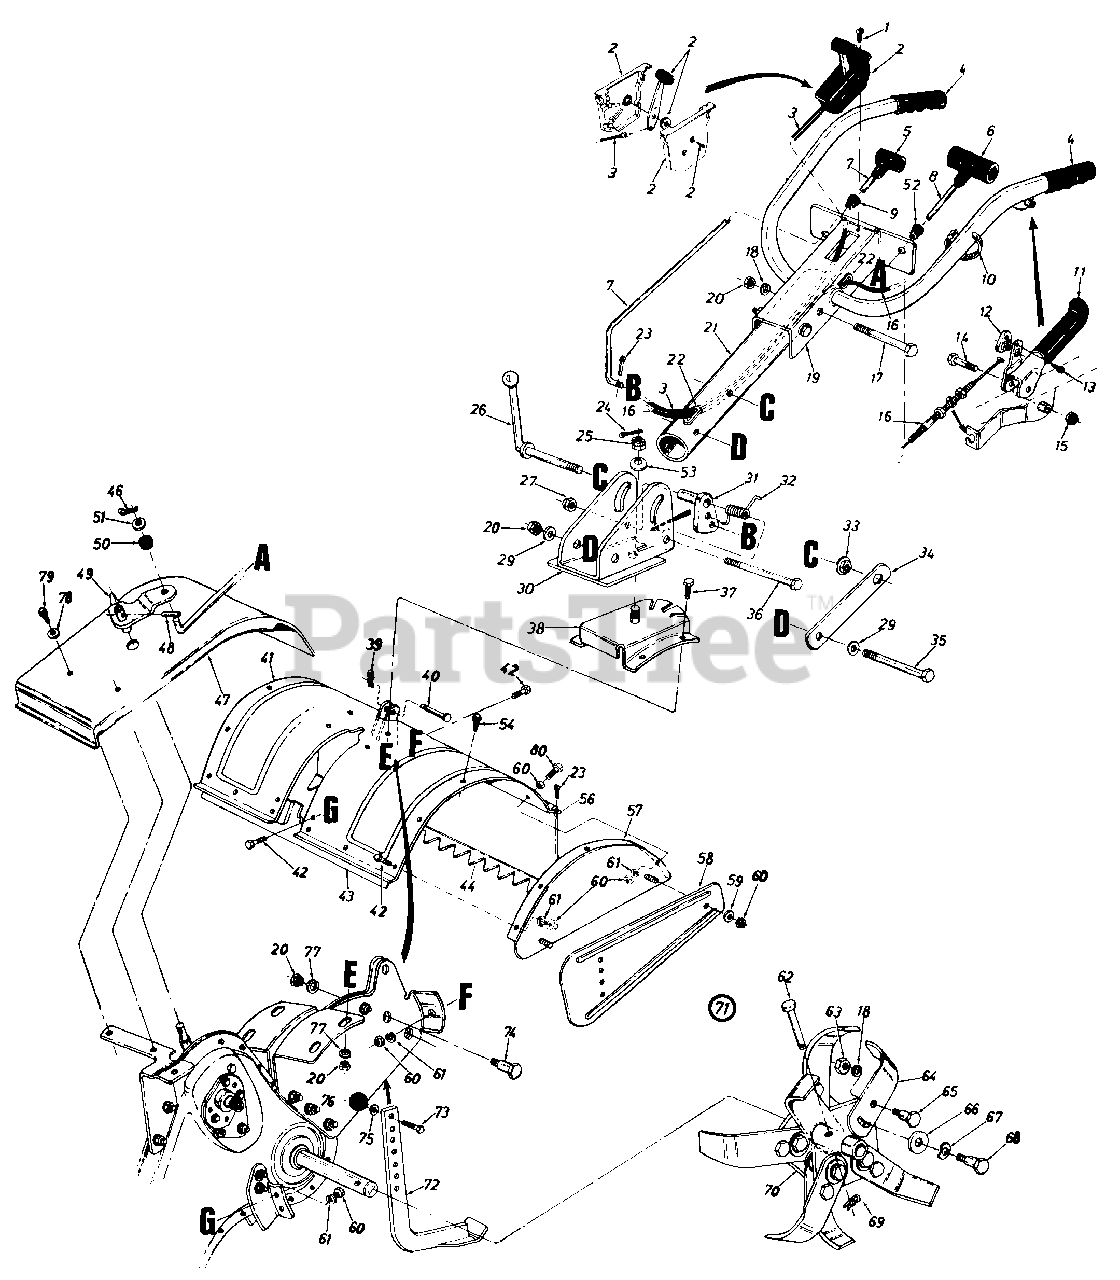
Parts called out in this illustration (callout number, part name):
1	Truss Mach. AB-Tap. Scr. #10 x .50' Lg.
2	Throttle Control Box Ass'y.
3	Throttle Control Wire
4	Handle Grip
5	Small "T" Knob
6	Large"T" Knob
7	Clutch Rod
8	Control Rod 37" Lg.
9	Snap On Bushing 3/8" Dia.
10	Cable Tie-Self Clinching
11	Clutch Grip Ass'y.-L.H.
12	Barrel Cable Hold Down
13	Hex B-Tap Scr. #10 x .44" Lg.
14	Hex Bolt 3/8"-16 x 2.0" Lg.
15	Hex Cent. L-Nut 3/8-16 Thd.
16	Clutch Control Cable 53" Lg.
17	Hex Bolt 3/8-16 x 3.00" Lg.
18	L-Wash. 3/8" l.D.-H.D.
19	Handle Ass'y.
20	Hex Nut 3/8-16 Thd.
23	Cotter Pin 3/32" Dia. x .75" Lg.
24	Cotter Pin 3/32" Dia. x 1.25" Lg.
25	Hex Slotted Nut 5/8-18 Thd.
26	Handle Adj. Crank
27	Hex Cent. L-Nut 3/8-16 Thd.
29	Bell-Wash. .4" I.D. x .87" O.D.
30	Handle Pivot Bracket
31	Positioner Crank Ass'y.
32	Spring Handle Adj. (Torsion)
33	Hex Flange Nut 3/8-24 Thd.
34	Bracket Hex Nut Retainer
35	Hex Bolt 3/8-16 x 3,25" Lg.
36	Hex Bolt 3/8-16 x 3.00" Lg.-Gr. 8
37	Hex Bolt 3/8-16 x .75" Lg.
40	Clevis Pin .375" Dia.
43	Bracket Reinforcement-18n
46	Intern. Cotter Pin 5/16" Dia.
49	Shifting Crank Ass'y.
50	Rubber Washer .33" l.D.
51	Fl-Wash. ,4" l.D. x 1.25" O.D.
52	Snap On Bushing t/2" Dia.
53	Bell-Wash. ,63" l.D. x 1.25n
54	Hex Wash. Tap Scr.
56	Tiller Flap Rod
57	483End Cover Ass'y.
60	Hex Nut 5/16-18 Thd.
61	L-Wash. 5/16" l.D.
62	Clevis Pin .375" Dia.
63	Hex Nut 3/8-24 Thd.
64	l3" Dia. Articulating Tine
65	Shld. Bolt 1/2" Dia. x .175
66	Fl-Wash. .51" l.D. x 1 .50"
67	Bell-Wash. .5l5" l.D. x 1.14"
68	Shld. Bolt /2" Dia. x .32t
69	Intern. Cotter Pin
70	Tine Adapter Ass'y. 18"
71	Tine Ass'y. Comp. 18"
72	Depth Bar Ass'y.
73	Hex Bolt 3/8-16 x .75" Lg.
74	Shld. Bolt 1/2" l.D. x .62" Lg.
75	Fl-Wash. 818" l.D. x 5/8" O.D.
76	Ball Knob
77	L-Wash. 818" l.D.
78	Fl-Wash. .281" l.D. x .62"
79	Hex Wash. Self-Tap Scr. 1/4-20 x .50" Lg.
80	Hex Bolt 5/16-18 x 11/4" Lg.
